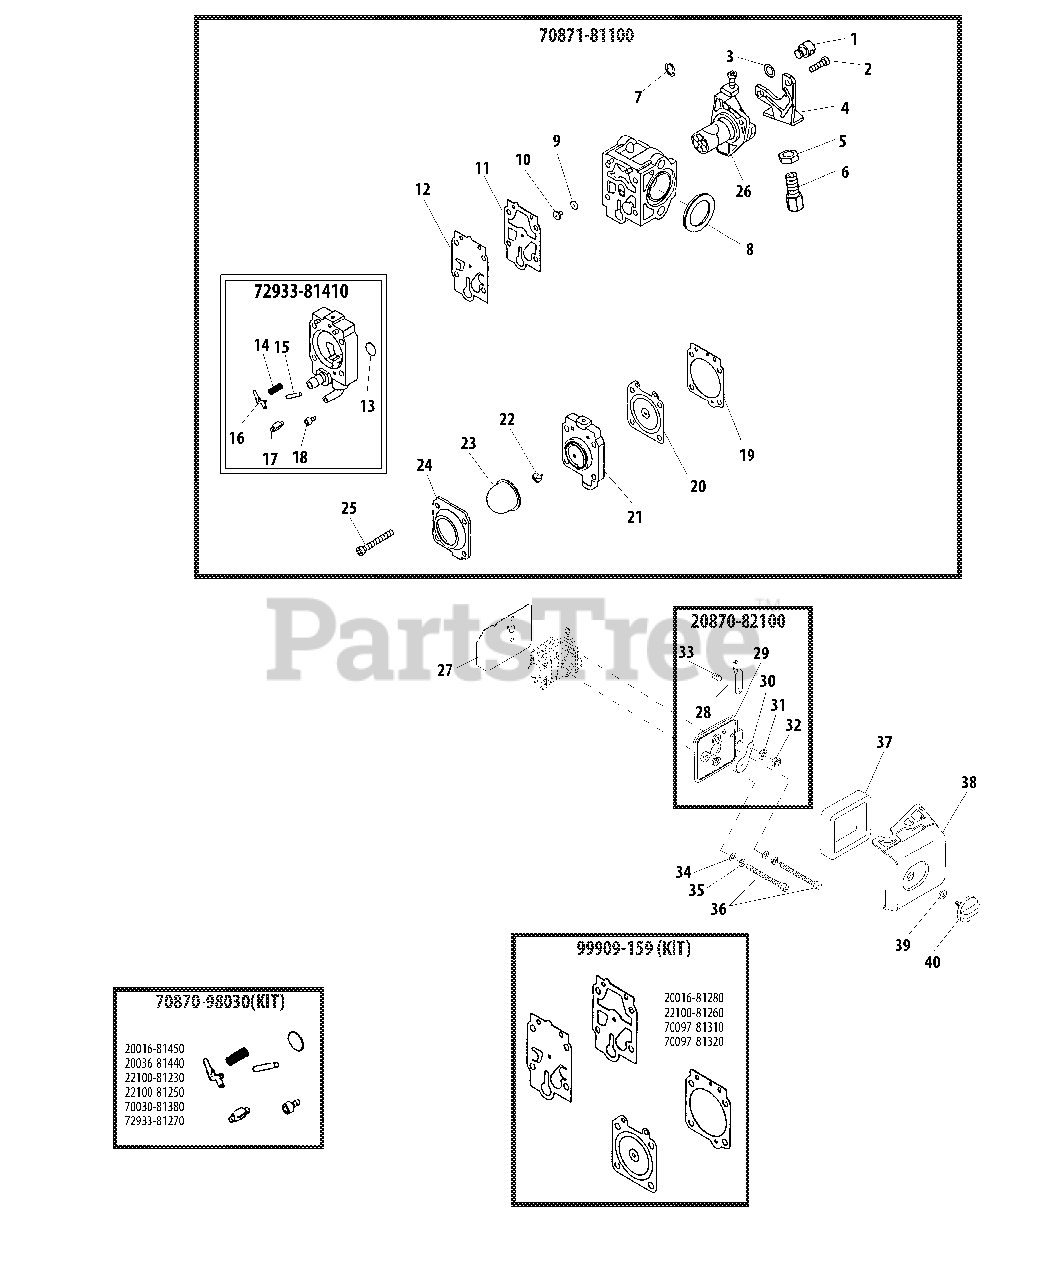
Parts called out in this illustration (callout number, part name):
1	SWIVEL
2	SCREW
3	WASHER
4	BRACKET, THROTTLE CABLE
5	NUT, ADJUSTER LOCK M7
6	ADJUSTER, THROTTLE CABLE
7	E-RING
8	RING, PACKING
9	O-RING
10	JET
11	GASKET, PUMP
12	DIAPHRAGM, PUMP
13	SCREEN, FUEL INLET
14	SPRING, METERING LEVER
15	PIN, METERING LEVER
16	LEVER, METERING
17	VALVE, INLET NEEDLE
18	SCREW
19	GASKET, METERING DIAPHRAGM
20	DIAPHRAGM, METERING
21	BODY ASSY, PURGE
22	VALVE, CHECK
23	BULB, PURGE
24	RETAINER, PURGE BULB
25	SCREW
26	THROTTLE VALVE ASSY
27	GASKET
28	LEVER, CHOKE
29	CASE, AIR FILTER
30	PLATE, CHOKE
31	WASHER, SPRING 6
32	U-NUT M6
33	SHAFT, CHOKE
34	WASHER, FLAT 5.5×10×0.8
35	WASHER, SPRING 5
36	BOLT 5×60
37	FILTER, AIR
38	COVER, AIR FILTER
39	WASHER 5
40	THUMBSCREW
20870-82100	AIR FILTER CASE ASSY
70870-98030	VALVE KIT, INLET NEEDLE
70871-81100	CARBURETOR
72933-81410	BODY ASSY, PUMP
99909-159	GASKET / DIAPHRAGM KIT
